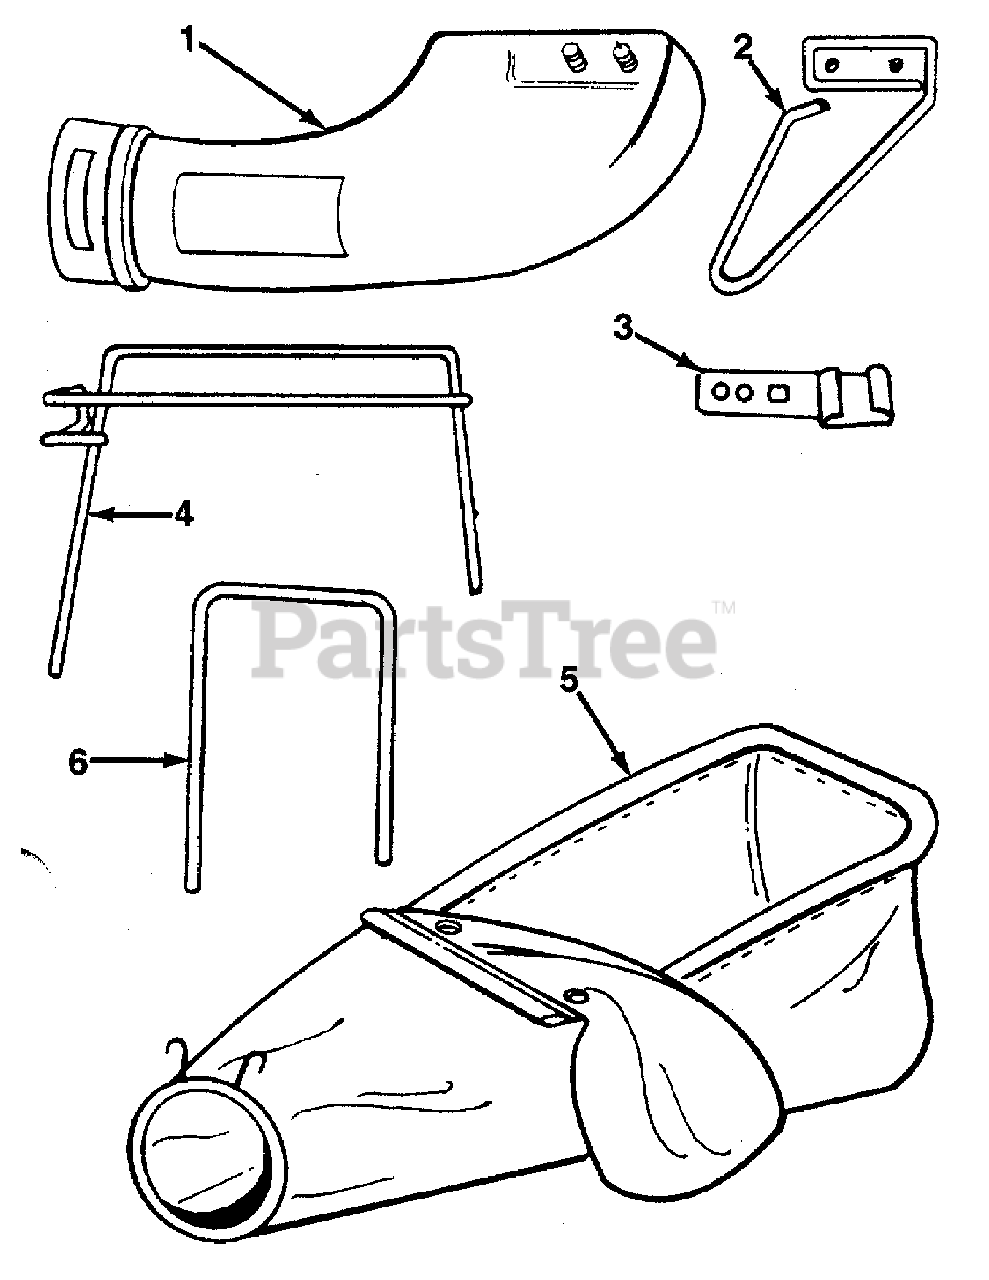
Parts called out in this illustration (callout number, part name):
1	Plastic Chute
2	Chute Mounting Bracket w/ wire
3	Handle Bracket
4	Bag Frame
5	Bag w/clamp ring
6	Upper Support Tube
